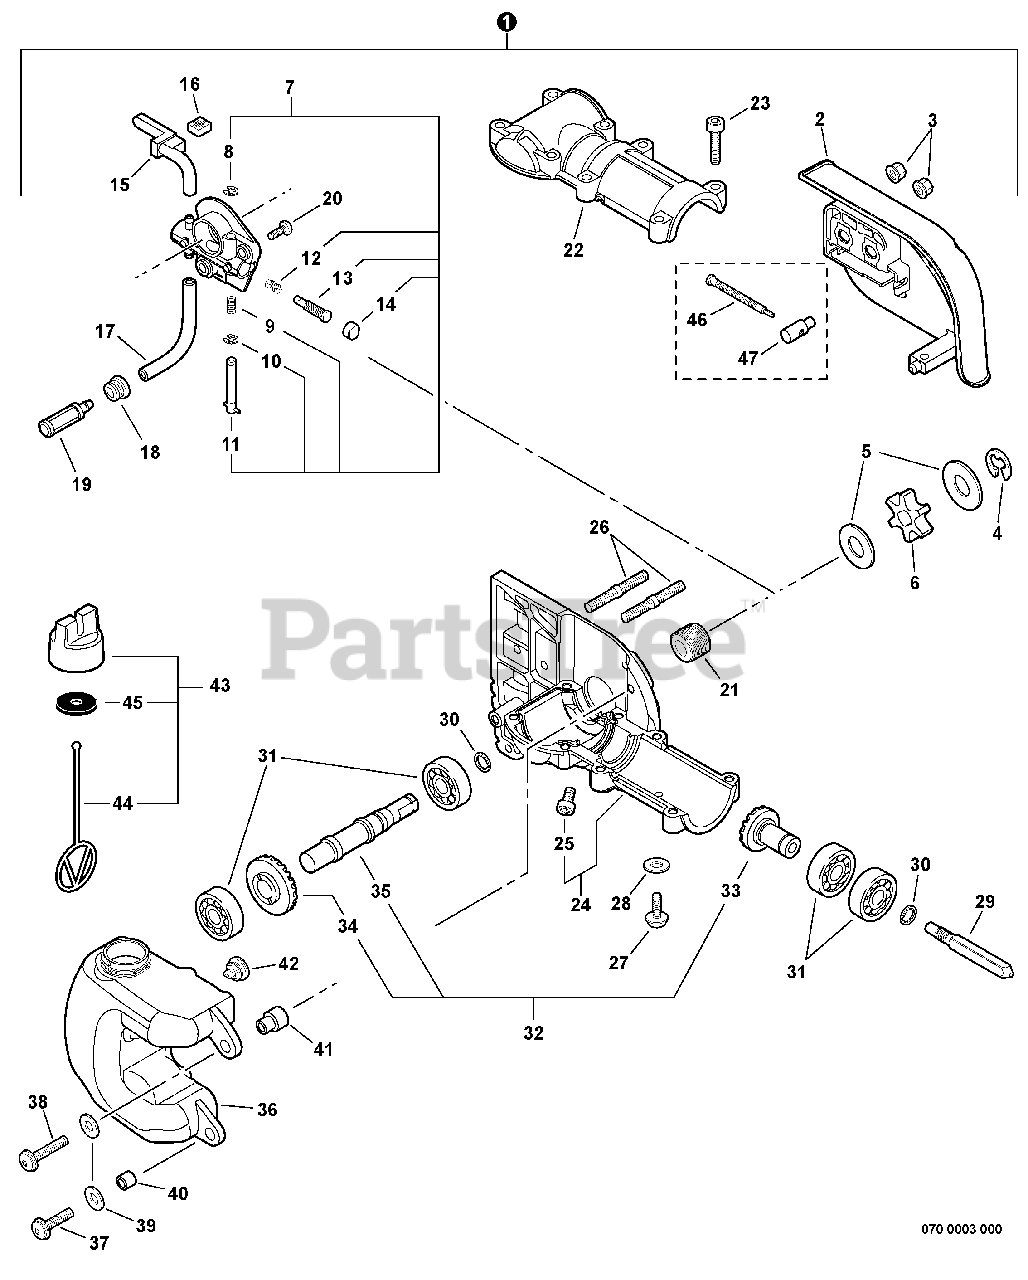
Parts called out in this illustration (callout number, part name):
1	OILER/GEAR CASE ASSY
2	GUARD, SPROCKET
3	NUT - 6 -- FLANGE
4	RING, RETAINING
6	SPROCKET, DRIVE
7	AUTO-OILER ASSY
8	RING, RETAINING
11	NEEDLE, ADJUST
12	SPRING, PLUNGER
13	PLUNGER ASSY
14	CAP, OIL PUMP
15	PIPE, OIL OUTLET
16	PAD, FOAM
17	PIPE - 3X6X75 -- BLACK
18	GROMMET
19	FILTER, OIL
20	SCREW - 5X10
21	GEAR - WORM
22	CASE, GEAR - UPPER
23	SCREW - 5X25
24	GEAR CASE ASSY - LOWER
25	SCREW - 5X10
26	STUD - 6
27	SCREW - 5X10
28	WASHER - 5
29	CONNECTOR, SHAFT
30	RING, RETAINING - 12
31	BEARING, BALL - 6001
32	GEAR SET
33	GEAR - BEVEL
34	GEAR - BEVEL
35	GEAR - SHAFT
36	TANK, OIL
37	SCREW - 5X16
38	SCREW - 5X25
39	WASHER - 5
43	CAP ASSY
44	CONNECTOR, CAP
45	GASKET, CAP
46	SCREW, TENSIONER
47	TENSIONER, CHAIN
